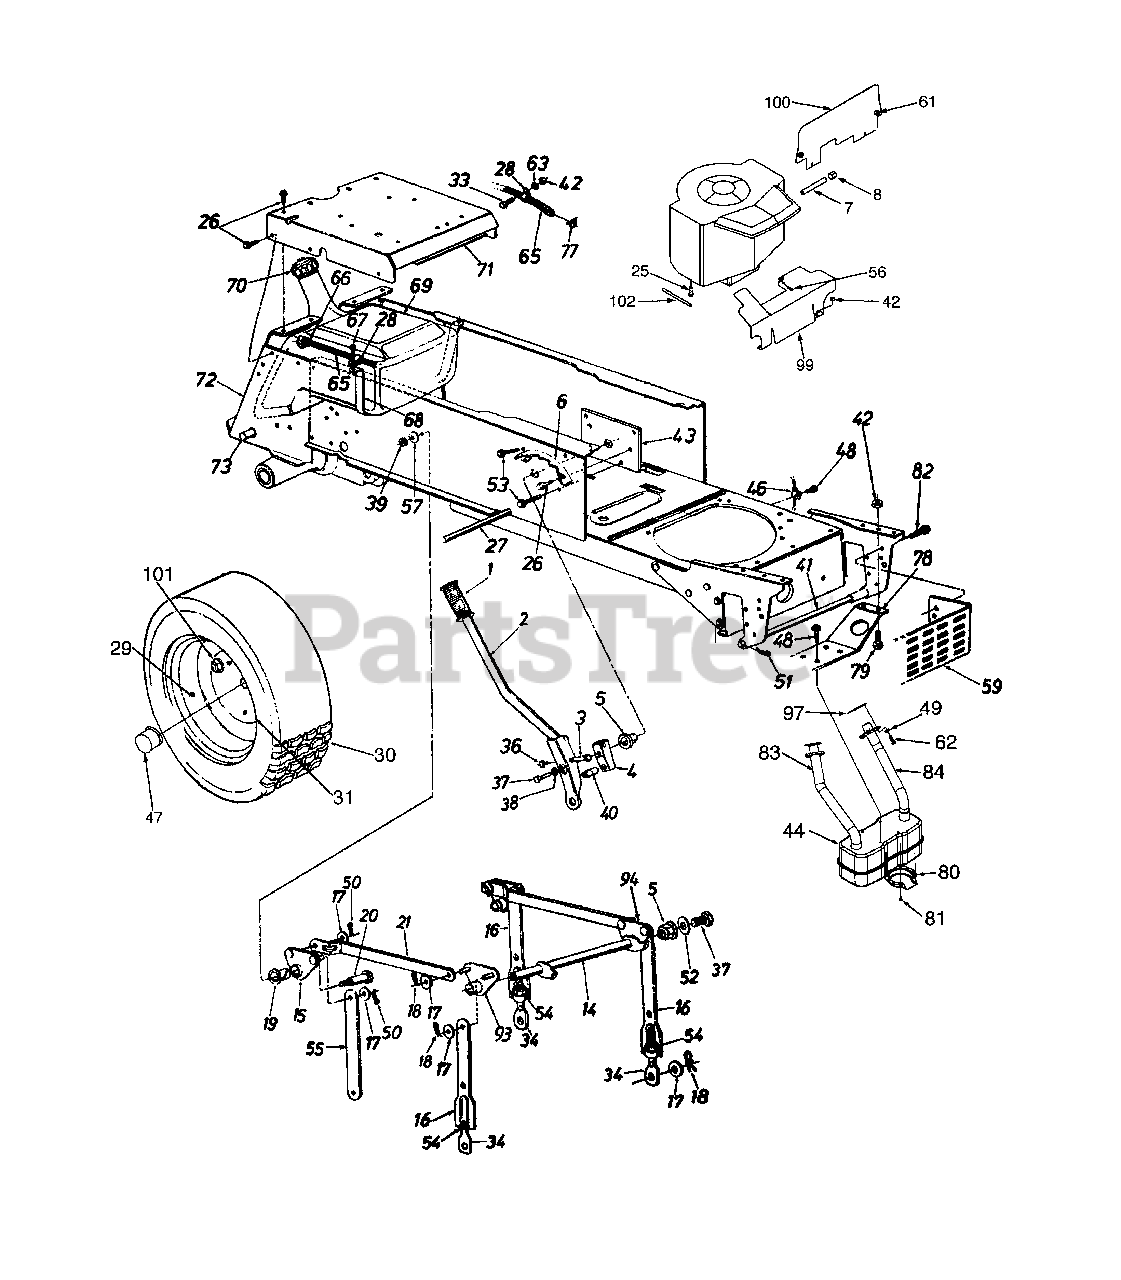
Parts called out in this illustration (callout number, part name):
1	Grip
4	Lift Shaft Drive
5	Plastic Hex Brg. 5/8" I.D.
8	Oil Drain Cap
14	Lift Shaft Ass'y.
15	Lift Pivot Brkt. Ass'y.
17	Fl-Wash. 1/2" I.D. x 1.00" O.D. x .090"
18	Hairpin Cotter
19	Flange Brg. .63" I.D.
20	Shld. Bolt 5/8" Dia. x .96" Lg. 3/8-16
26	Hex Thd. Rolling Scr. 5/16-18 x .75" Lg.
27	Running Board Rod
28	Clamp
29	Air Valve
33	Hex Bolt 1/4-20 x .62" Lg.
34	Eye Bolt Adj. Link 1/2-13 Thd.
36	Hex Cent. L-Nut 5/16-18 Thd.
37	Hex Bolt 5/16-24 x .62" Lg.
39	Hex Top L-Nut 3/8-16 Thd.
40	Compression Spring
41	Deck Connecting Rod
42	Hex Sems Nut 1/4-20 Thd.
46	Mounting Clamp
47	Hub Cap
48	Hex TT-Tap Scr. 1/4-20 x .5" Lg.
49	L-Wash. 5/16" I.D.
50	Cotter Pin .09 Dia. x 1.0" Lg.
51	Int. Cotter Pin
52	Flat Wash. .34" I.D. x 1.12" O.D. x .125"
53	Hex AB-Tap Scr. 5/16-24 x .5"
54	Hex Nut 1/2-13 Thd.
56	Hex Slot Scr. #10 x .44" Lg.
57	Bell-Wash. .4" I.D. x 1.13" O.D.
62	Hex Bolt 5/16-18 x .75" Lg.
63	L-Wash. 1/4" I.D.
65	Fuel Line 60" Lg.
66	Hose Clamp
67	Hex AB-Tap Scr. 1/4 x .62" Lg.
68	Fuel Tank Strap
69	Gas Tank
70	Gas Gauge
71	Seat Plate
77	Hose Clamp
78	Muffler Mounting Brkt.
79	Hex Bolt 1/4-20 x .62" Lg.
80	Muffler Deflector
81	Hex F-Tap Scr. #8 x .32" Lg.
82	Hex TT-Tap Scr. 5/16"-18 x .62"
83	Exhaust Tube-R.H.
84	Exhaust Tube-L.H.
93	Pivot Brkt. Ass'y.-R.H.
94	Pivot Brkt. Ass'y.-L.H.
97	Gasket
99	Lower Heat Shield
100	Upper Heat Shield
101	Lug Nut 7/16-14 Thd.
102	Trim Strip 10" Lg.
